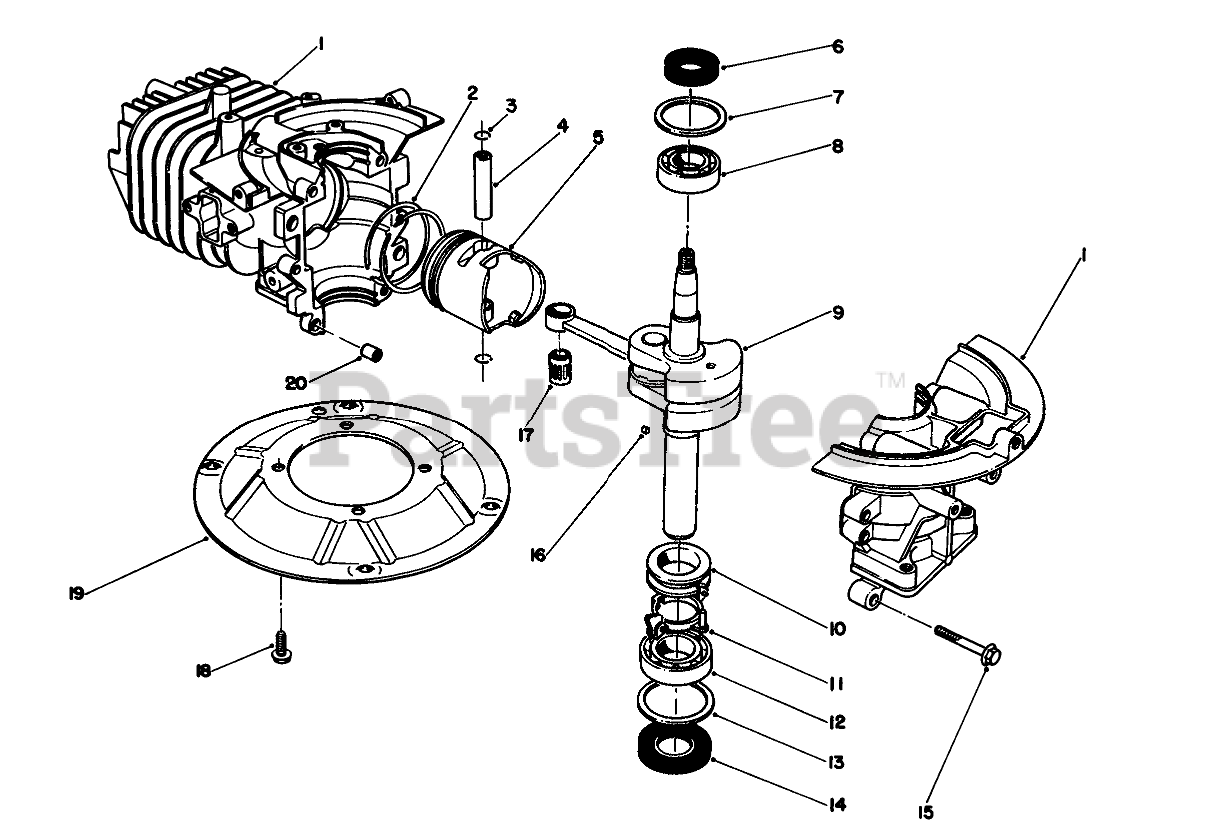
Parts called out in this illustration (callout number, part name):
1	CRANKCASE
2	RING SET
4	PIN-PISTON
5	PISTON
6	OIL SEAL
7	WASHER-UPPER
8	BEARING-UPPER
9	CRANKSHAFT
10	SPACER
11	BRACKET
12	LOWER BRG
13	WASHER-LOWER
14	SEAL-OIL
17	BEARING
19	PLATE-MOUNTING
